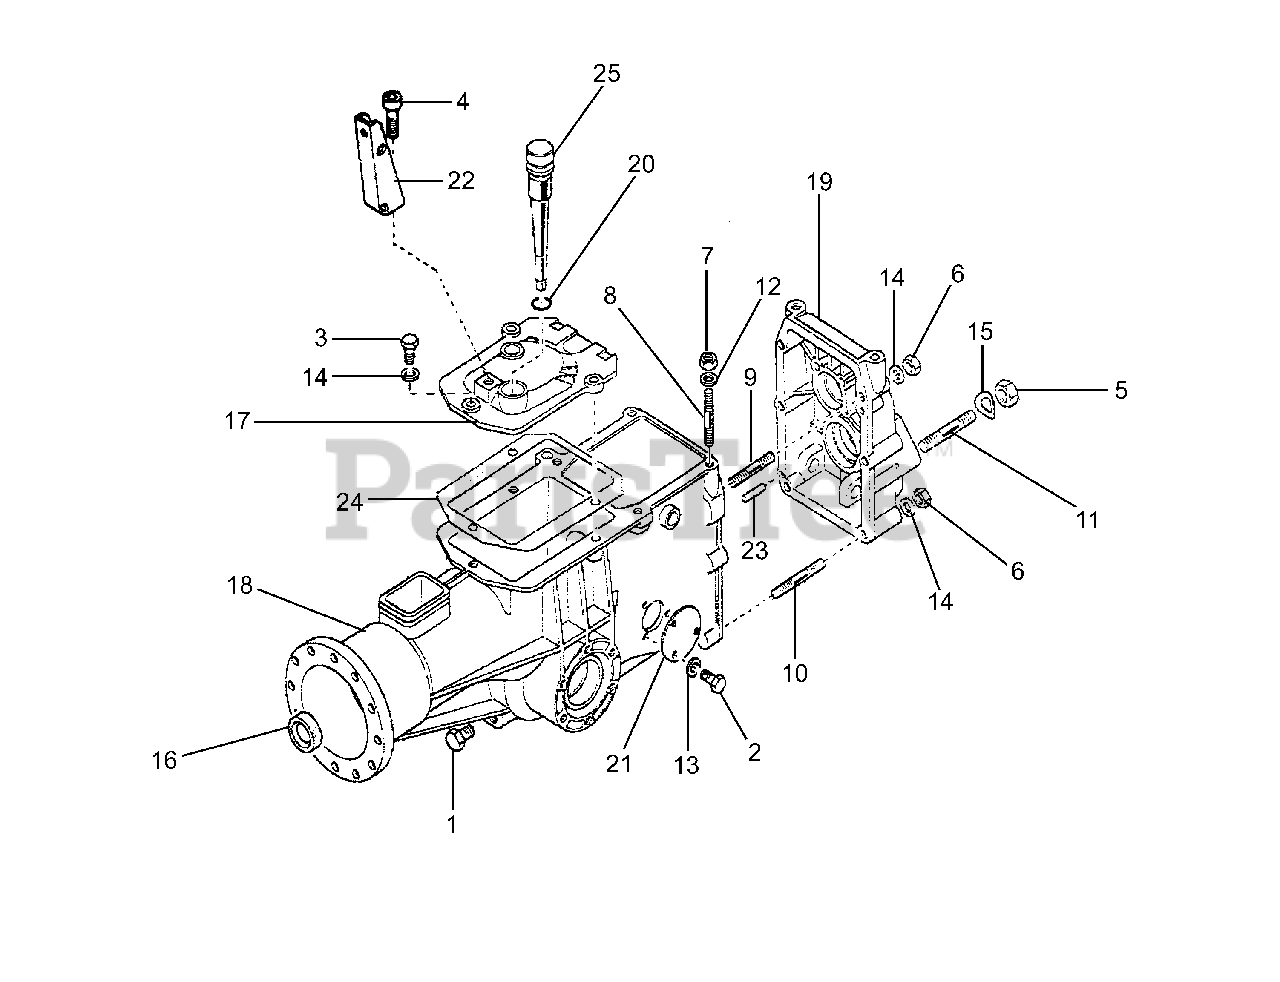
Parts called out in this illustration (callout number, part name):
1	PLUG 1/4 GAS UNI 364
2	HEX. SCREW M6X10 UNI 5739 8G
3	HEX. SCREW M8X25 UNI 5739-8G
4	SCREW M10X25
5	NUT M12X1.25 UNI 5587 6S
6	LOCKNUT M 8
7	LOCKING NUT M8 DEFORM.6S
8	STUD M8X38X14X20
9	STUD M8X58X16X16 8G
10	STUD M8X70X16X16 8G
11	STUD 56XM12X1.25X26XM12X22 8G
12	SUPER WASHER 8 DIN6796 GALV.
13	SPRING WASHER 6.4 DIN 137
14	SPRING WASHER B 8.4 DIN 137
15	SPRING WASHER B 13 DIN 137
16	OIL SEAL 15X28X6
17	CLOSED GEARBOX COVER
18	GEARBOX CASING
20	RING RUBBER
21	SIDE BOX COVER
22	LONG STOP BRACKET
23	PARALLEL PIN D 6X20
25	CAP WITH MEASURING ROD
